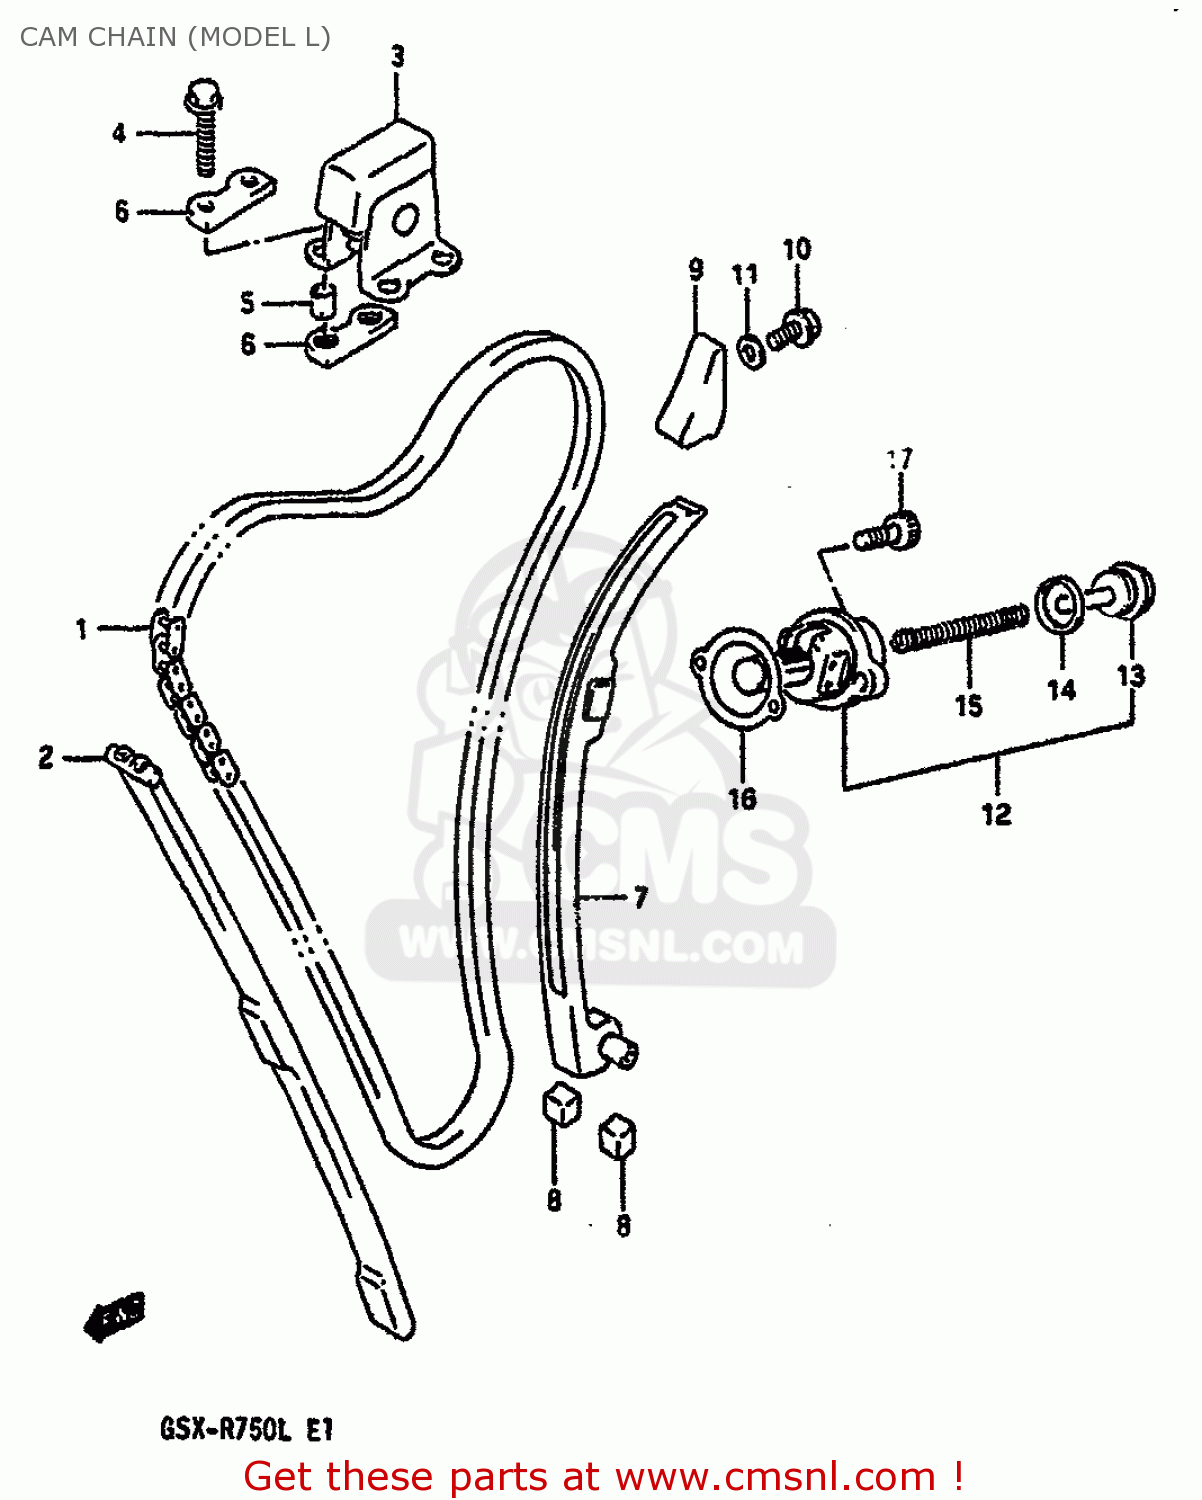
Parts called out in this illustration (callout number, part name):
1	CHAIN,CAMSHAFT DRIVE
2	GUIDE,CAM CHAIN NO.1
3	IDLER,CAM CHAIN
4	BOLT 6X25
5	SPACER
6	CUSION,IDLER
7	TENSIONER,CAM CHAIN
8	CUSHION,CAM CHAIN TENSIONER
9	GUIDE,CAM CHAIN NO.2
10	BOLT
11	GASKET(5.8X13X1.2) (NAS)
12	ADJUSTER ASSEMBLY,TENSIONER
13	PLUG
14	GASKET (NAS)
15	SPRING
16	GASKET,TENSIONER ADJUSTER (NAS)
17	BOLT
18	BOLT
